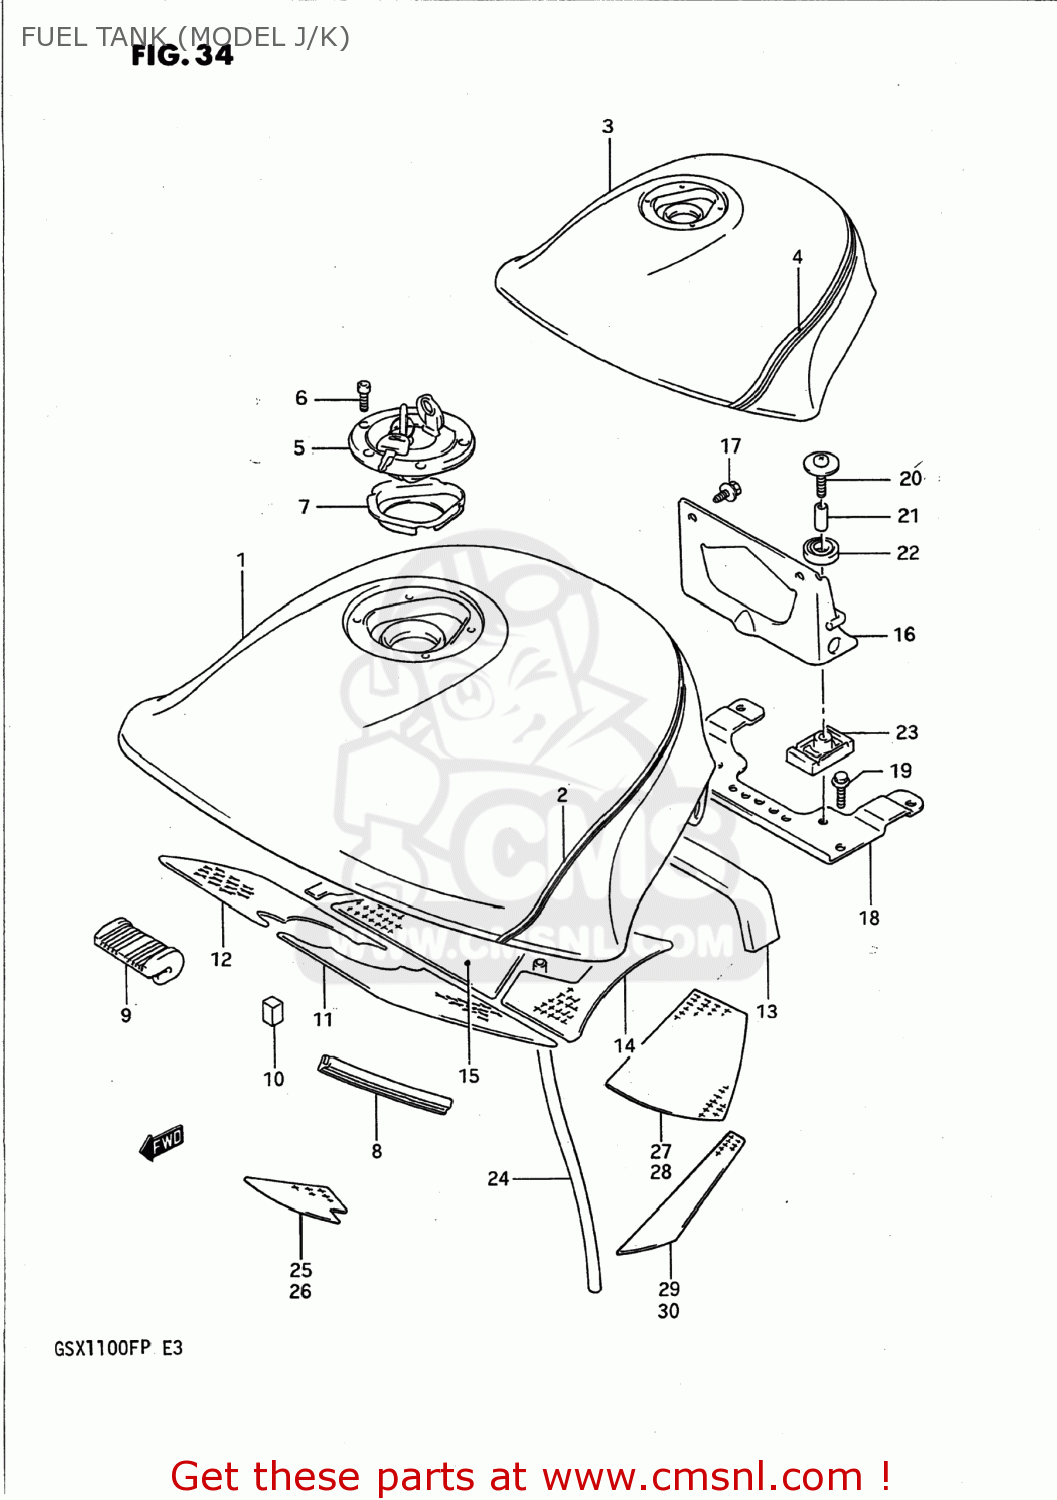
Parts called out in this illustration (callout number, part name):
1	TANK ASSEMBLY,FUEL
2	TAPE SET,FUEL TANK
3	TANK ASSEMBLY,FUEL
4	TAPE,FUEL TANK
5	CAP SET,FUEL TANK
6	BOLT(5X10)
7	COVER,FUEL TANK INLET
8	MOLDING,FUEL TANK
9	CUSHION,FUEL TANK FR
10	CUSHION,FUEL TANK SIDE
11	HEATSHIELD,FUEL TANK FR,L
12	HEAT SHIELD,FUEL TANK
13	HEAT SHIELD,FUEL TANK
14	HEATSHIELD,FUEL TANK RR,L
15	HEAT SHIELD,FUEL TANK
16	BRACKET COMP,FUEL TANK
17	SCREW(6X16)
18	BRACKET,FUEL TANK RR LOW
19	BOLT 6X20
20	BOLT L:35,WITH WASHER
21	SPACER (6.4X9X21.5)
22	CUSHION
23	CUSHION
24	HOSE (7X10.2X1000)
25	HEAT SHIELD,FUEL TANK
26	HEAT SHIELD,FUEL TANK
27	HEAT SHIELD,FUEL TANK
28	HEAT SHIELD,FUEL TANK
29	HEAT SHIELD,FUEL TANK
30	HEAT SHIELD,FUEL TANK
